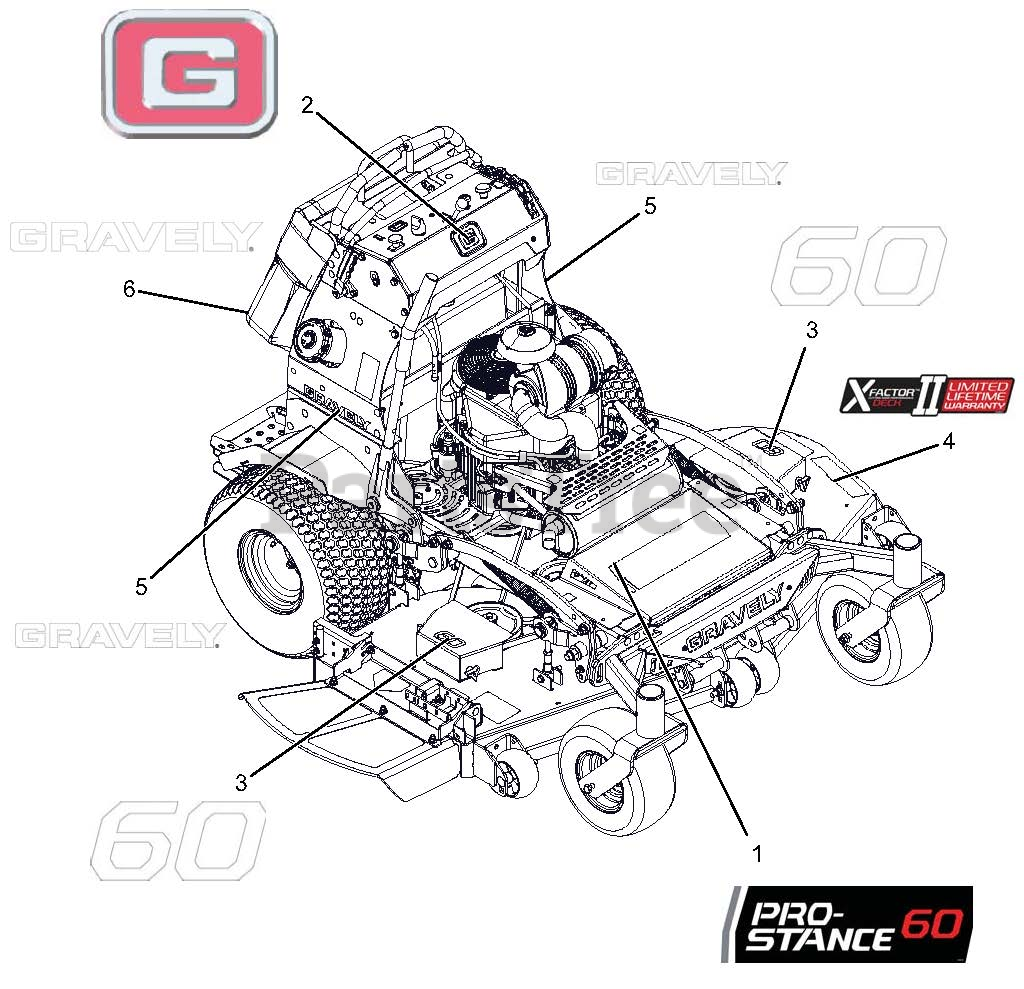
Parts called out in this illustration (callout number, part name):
1	DECAL, PROSTANCE 60
2	DECAL, GRAVELY BRAND
3	DECAL, 60"
4	DECAL, X-FACTOR DECK
5	DECAL, 9.5" GRAVELY LOGO
6	DECAL, 13.5" GRAVELY LOGO
